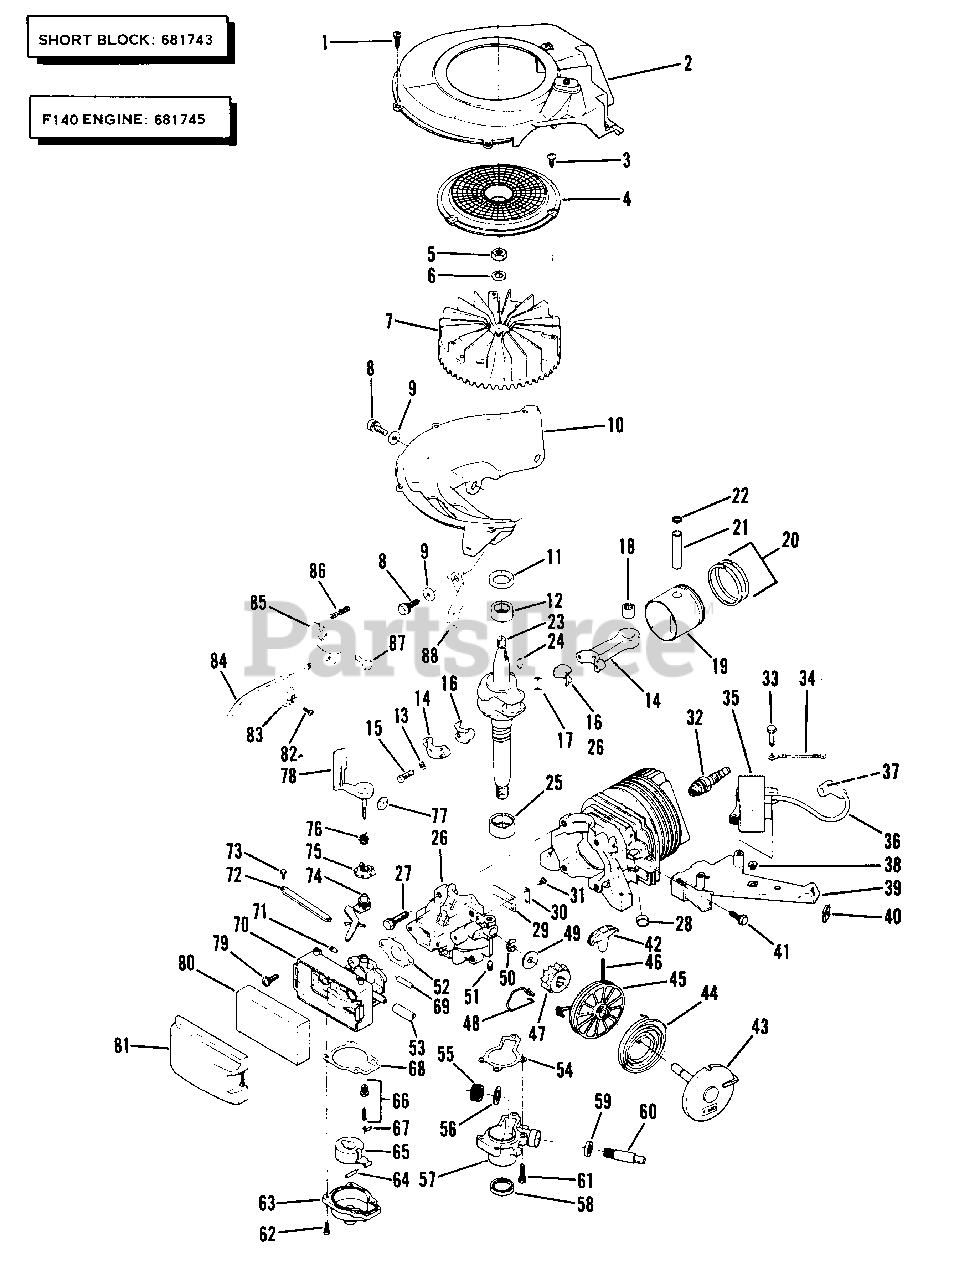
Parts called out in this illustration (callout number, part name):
1	Screw
2	Air Baffle & Eyelet Assembly
3	Screw-Flywheel Screen
4	Screen-Flywheel
5	Nut-Flywheel
6	Lockwasher
7	Flywheel Assembly
8	Screw
9	Washer
10	Base-Shroud
11	Oil Seal-Upper
12	Bearing-Upper
13	Lockplate
14	Connecting Rod Assembly
15	Screw
16	Liner-Split
17	Needle Bearing Set
18	Bearing Assembly
19	Piston & Ring Set
20	Ring Set
21	Wrist Pin
22	Retaining Ring
23	Crankshaft
24	Key-Flywheel
25	Bearing-Lower
26	Cylinder & Crankcase Cover Assembly
27	Screw-Cover to Crankcase
28	Plug
29	Reed
30	Plate-Reed Hold Down
31	Screw-Reed to Crankcase Cover
32	Spark Plug
33	Screw-C.D. Mounting
34	Lead Assembly-Ignition
35	C.D. Ignition Module & Lead Assembly
36	High Tension Lead
37	Spring Terminal
38	Grommet-C.D. Bracket
39	Bracket-C.D. Mounting
40	Clip-"U"
41	Screw
42	Handle-Starter
43	Cup & Pin Assembly
44	Spring
45	Pulley
46	Rope
47	Pinion
48	Spring
49	Washer
50	Retainer
51	Set Screw-Starter Assembly
52	Gasket-Carburetor to Crankcase Cover
53	Fuel Line
54	Gasket-Gear Box
55	Gear
56	Washer-Thrust
57	Gear Box Assembly
58	Oil Seal
59	Seal
60	Driveshaft
61	Screw-Gear Box
62	Screw-Float Chamber
63	Float Chamber
64	Pin-Float
65	Float
66	Float Valve & Seat
67	Clip
68	Gasket
69	Tube-Primer
70	Carburetor Body
71	Screw-Altitude Adjustment
72	Retainer-Speed Control Lever
73	Screw
74	Speed Control Lever
75	Collar
76	Spring
77	Disk-Throttle
78	Air Vane & Shaft
79	Screw-Carburetor Mounting
80	Element-Air Filter
81	Cover-Air Filter
82	Screw-Clip-Cable Casing
83	Clip
84	Cable-Interlock
85	Lever-Lockout
86	Spring-Interlock
87	Bolt-Shoulder
88	Bracket-Cable
